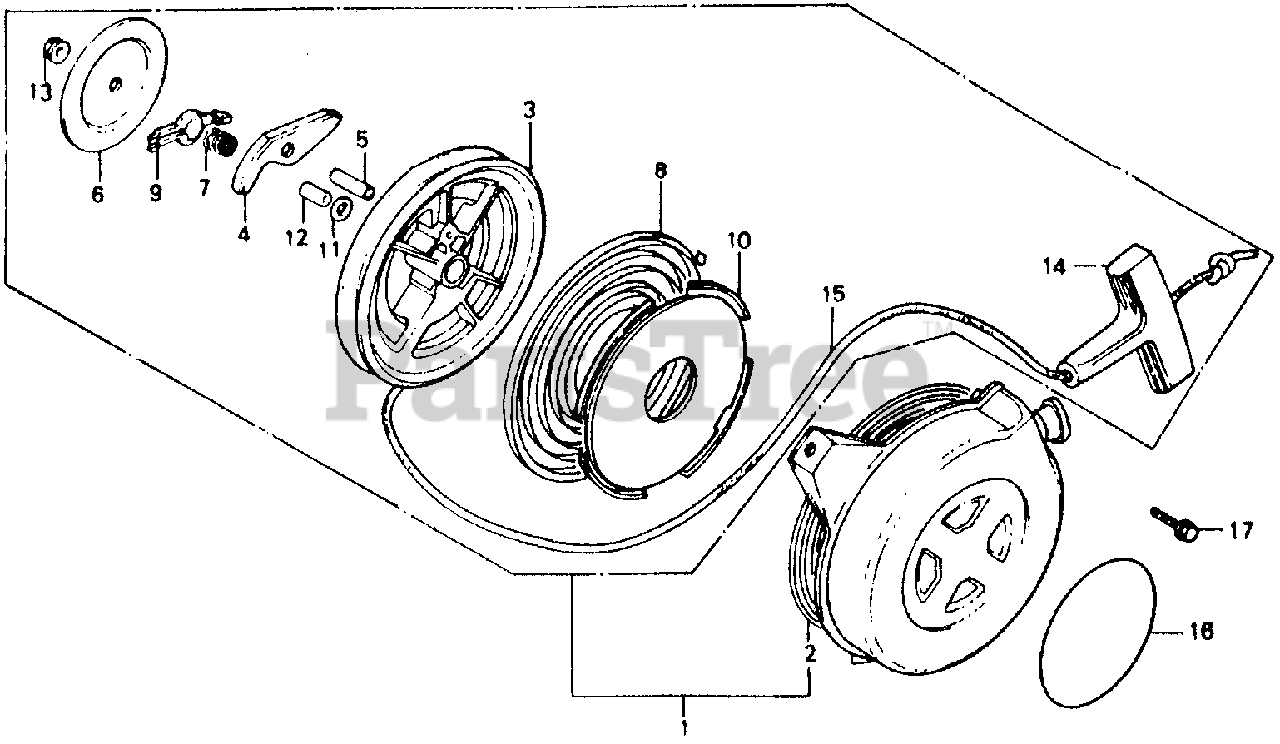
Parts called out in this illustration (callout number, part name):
1	STARTER ASSY., RECOIL *R8* (BRIGHT RED)
2	CASE, RECOIL STARTER *R8* (BRIGHT RED)
3	PULLEY, RECOIL STARTER
4	RATCHET, STARTER
5	PIN, STARTER RATCHET
6	PLATE, FRICTION
7	SPRING, FRICTION
8	SPRING, RECOIL STARTER
9	GUIDE, RATCHET
10	CASE, RECOIL STARTER SPRING
11	WASHER, STARTER
12	SHAFT, SUB
14	KNOB, RECOIL STARTER
15	ROPE, RECOIL STARTER (#5X59") (NA USE ALT:08550-ZG921-11)
16	EMBLEM (EXTERNAL-ALERT)
17	BOLT, FLANGE (6X10)
